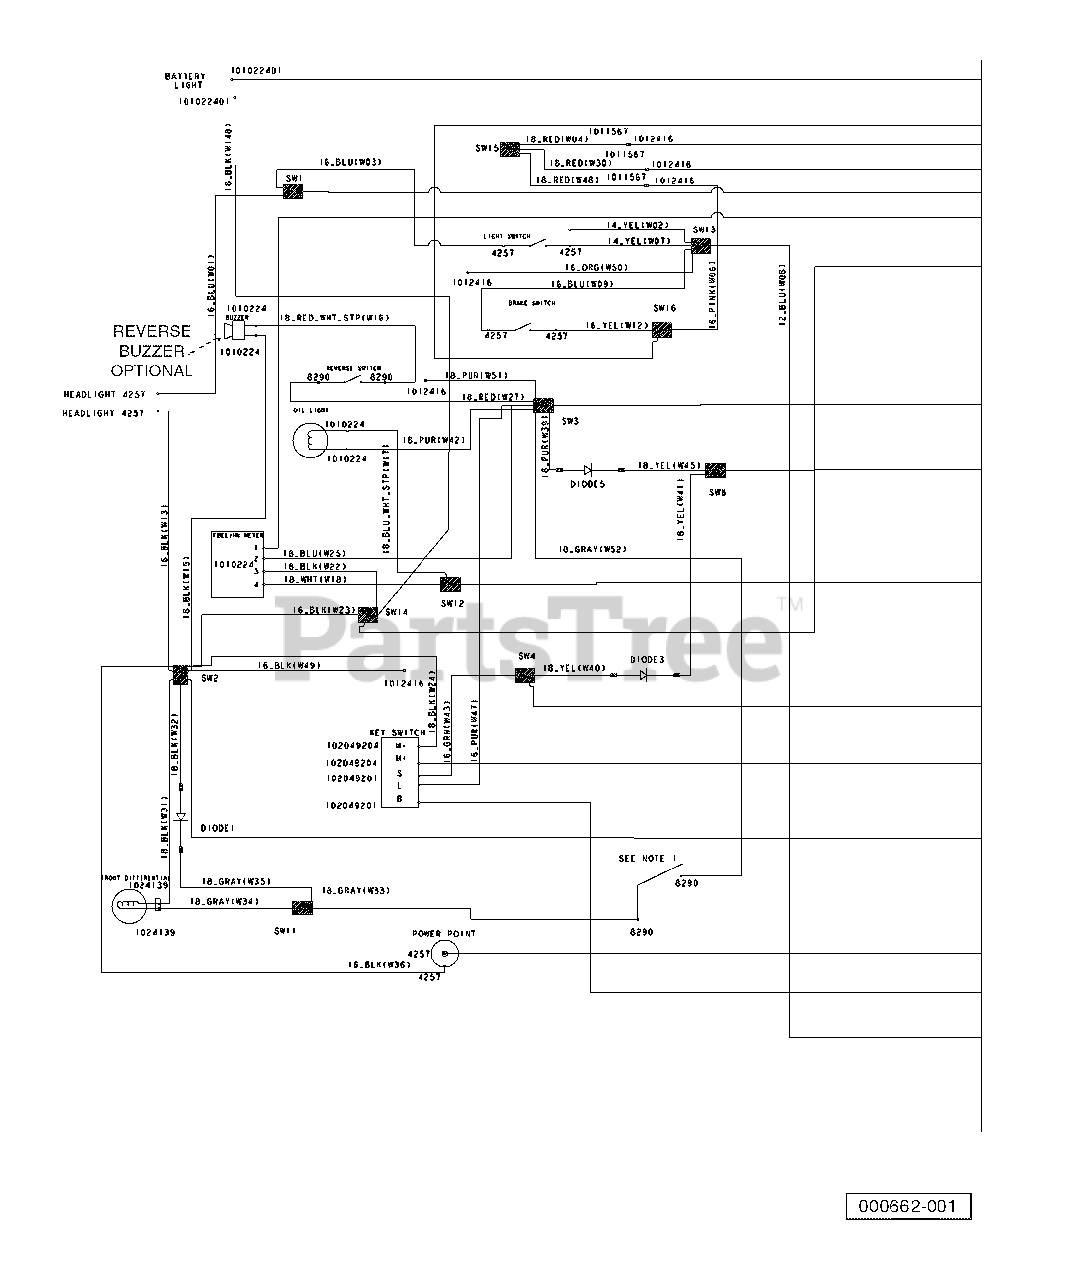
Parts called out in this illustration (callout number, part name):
1	Diode, General Purpose, 6.0a
2	Harness, AWD, Kawasaki
3	Asm, Switch, Limit, Awd
